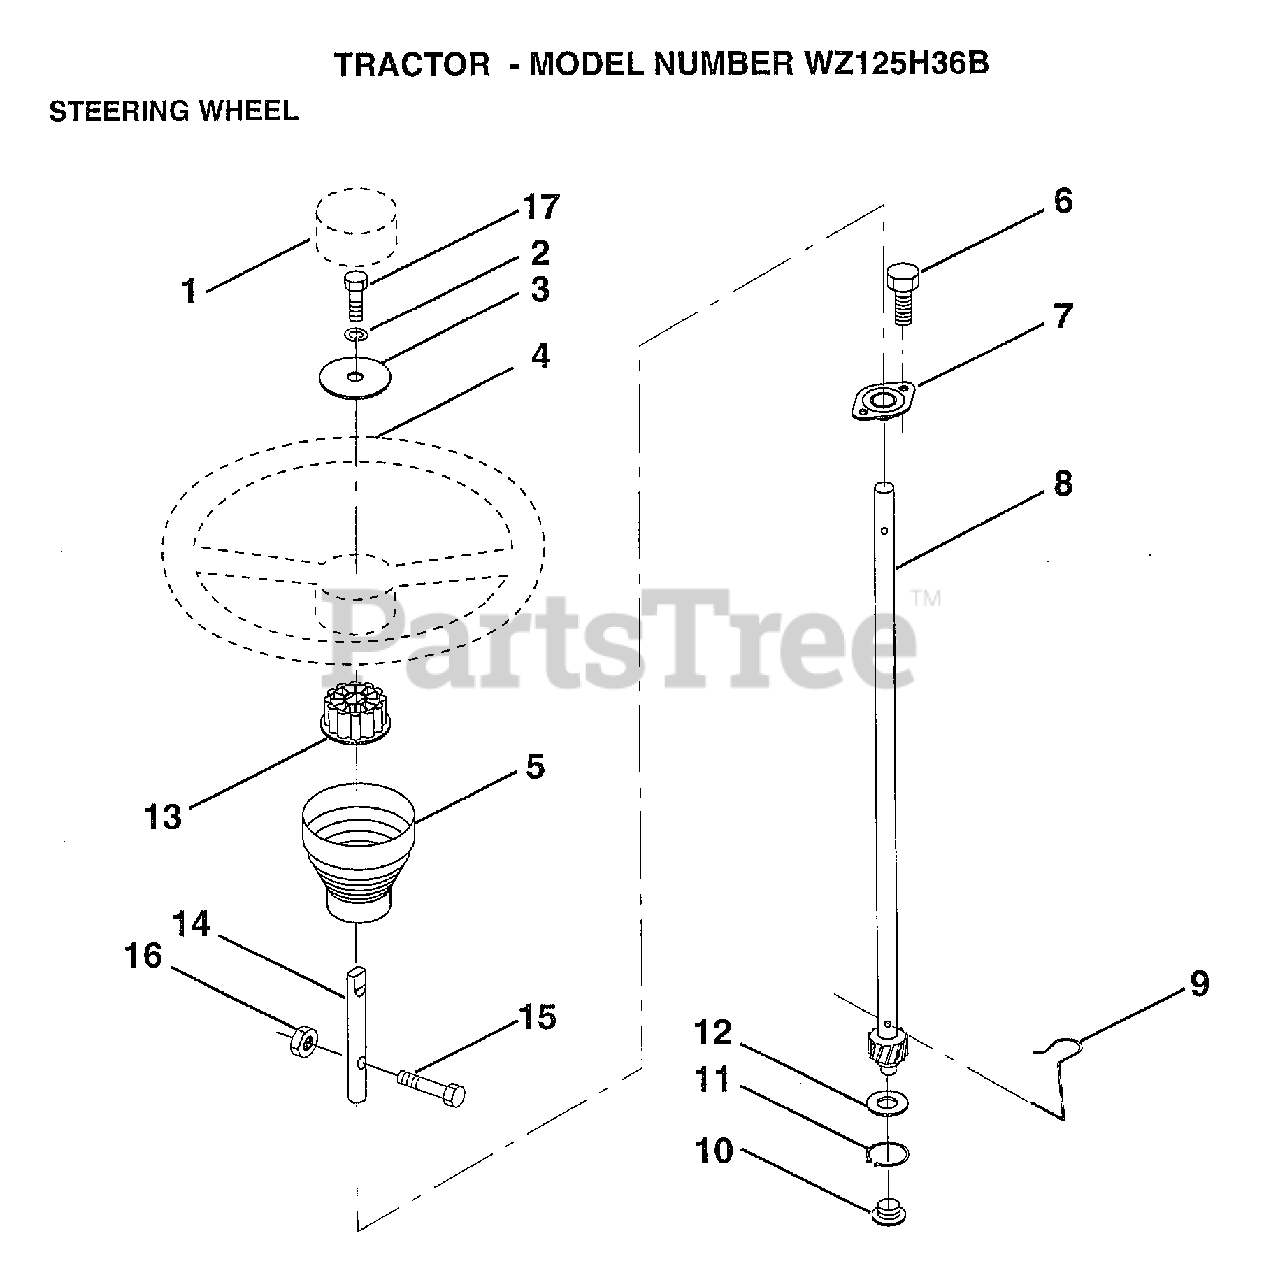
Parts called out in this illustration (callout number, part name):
1	CAP STEER AYP
2	LOCKWASHER
3	WASHER T
4	WHEEL STR AYP BLK
5	SLEEVE STEERING
6	"SCREW-TT,10-32 FL"
7	BUSHING.STR.623
8	SHAFT.STEERING.LR
9	STEERING CLIP
10	BUSHING STEER LWR
11	RING
12	WASHER LT
13	ADAPTER LT
14	EXT SHAFT STEERIN
15	BOLT
16	NUT
17	BOLT
